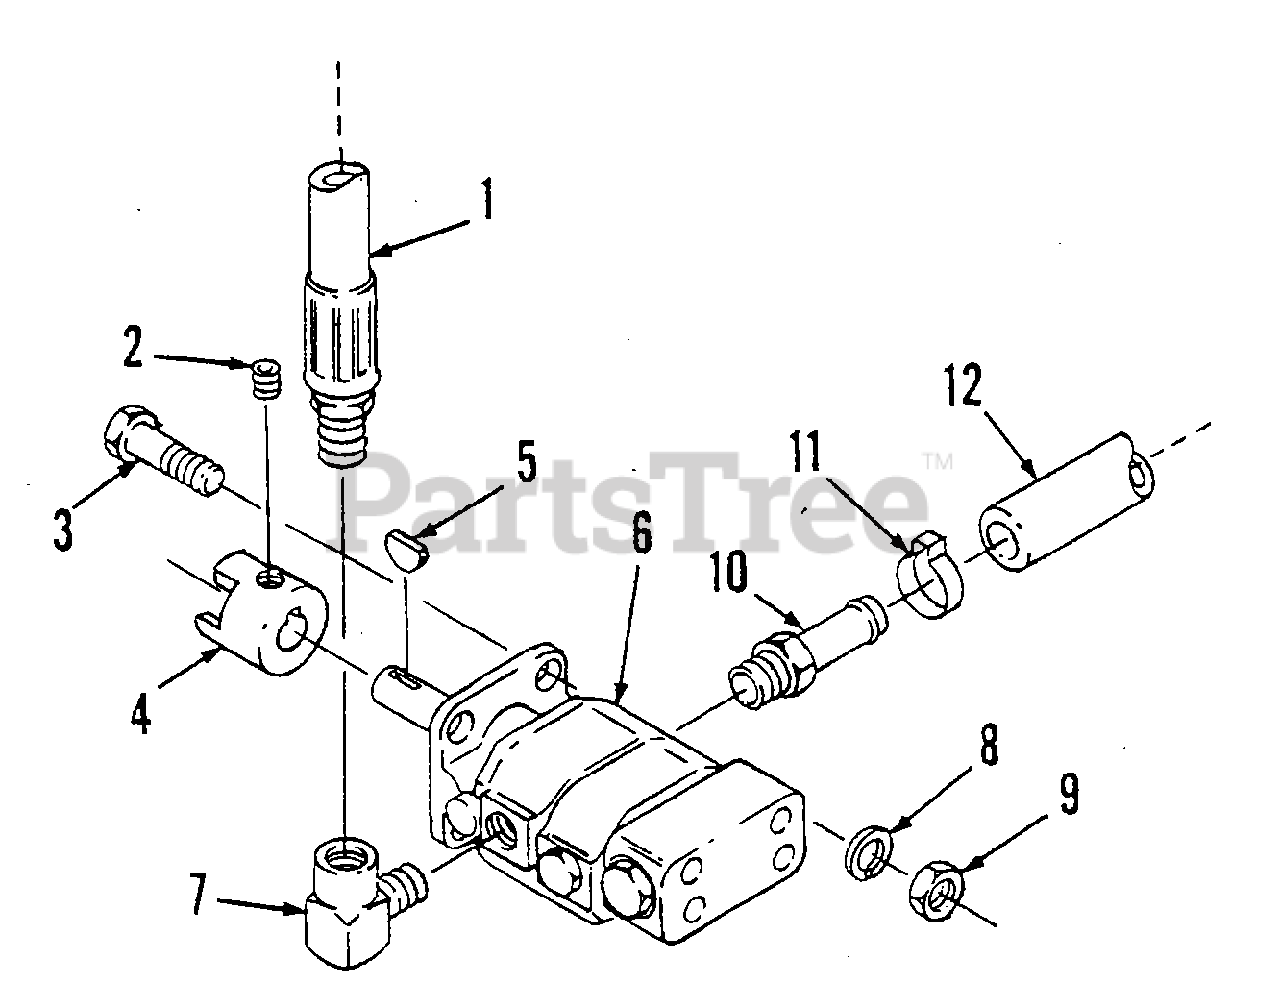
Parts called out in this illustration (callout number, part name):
1	Pressure Hose Assembly
3	Hex Head Bolts (5/16-18 x 1", Gr. 8) (4 used)
4	Hub Coupling (1/2")
5	Woodruff Key (1/8")
6	Hydraulic pump (Style "B")
7	90deg Street Ell (1/2 NPT)
8	Split Lock Washers (5/16) (4 used)
9	Fin. Hex Nut (5/16-18) (4 used)
10	Straight fitting (1/2 NPT x 5/8)
11	Hose clamp (2 used)
12	Suction hose
